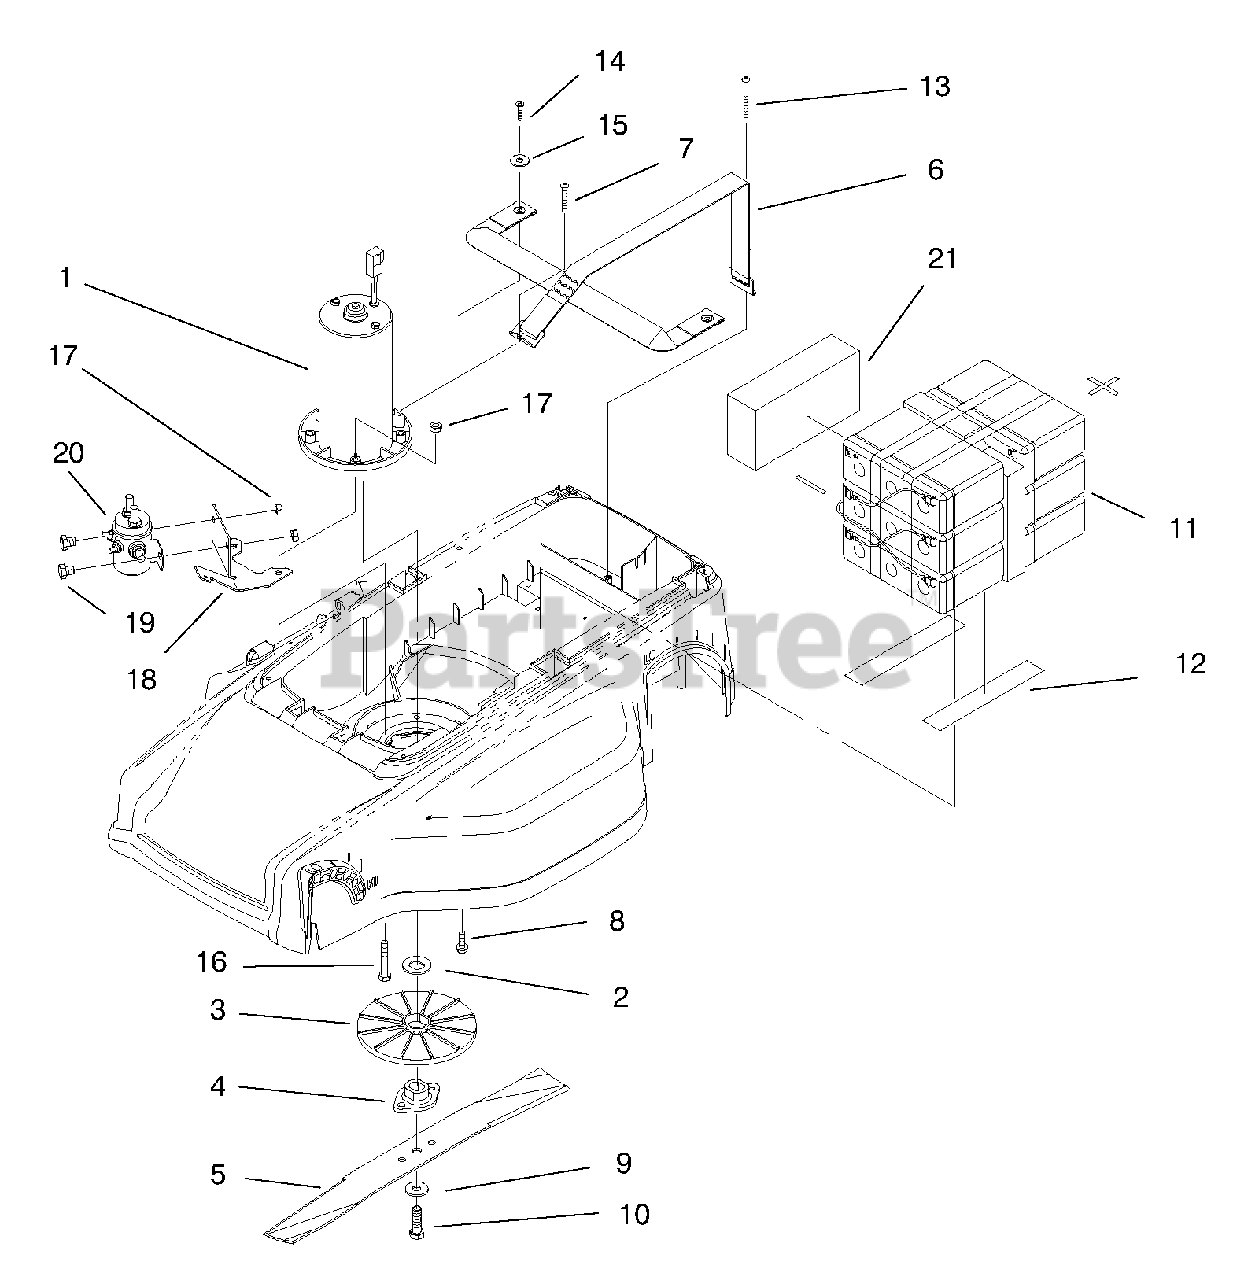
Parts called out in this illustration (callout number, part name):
1	ASM-Motor 36 Volt
5	Blade
6	ASM-Battery Strap
7	Screw-PPH
8	Screw-HWHTF
9	Washer-Spring
10	Bolt-Blade
11	ASM-Battery (Incl. Ref #12)
12	Tape-Foam
13	Screw-PPH
15	Washer-Flat
16	Screw-HWHTF
17	Nut-Lock
18	Bracket-Solenoid
19	Screw-HHF
20	Solenoid-36 Volt
21	Spacer-Foam
